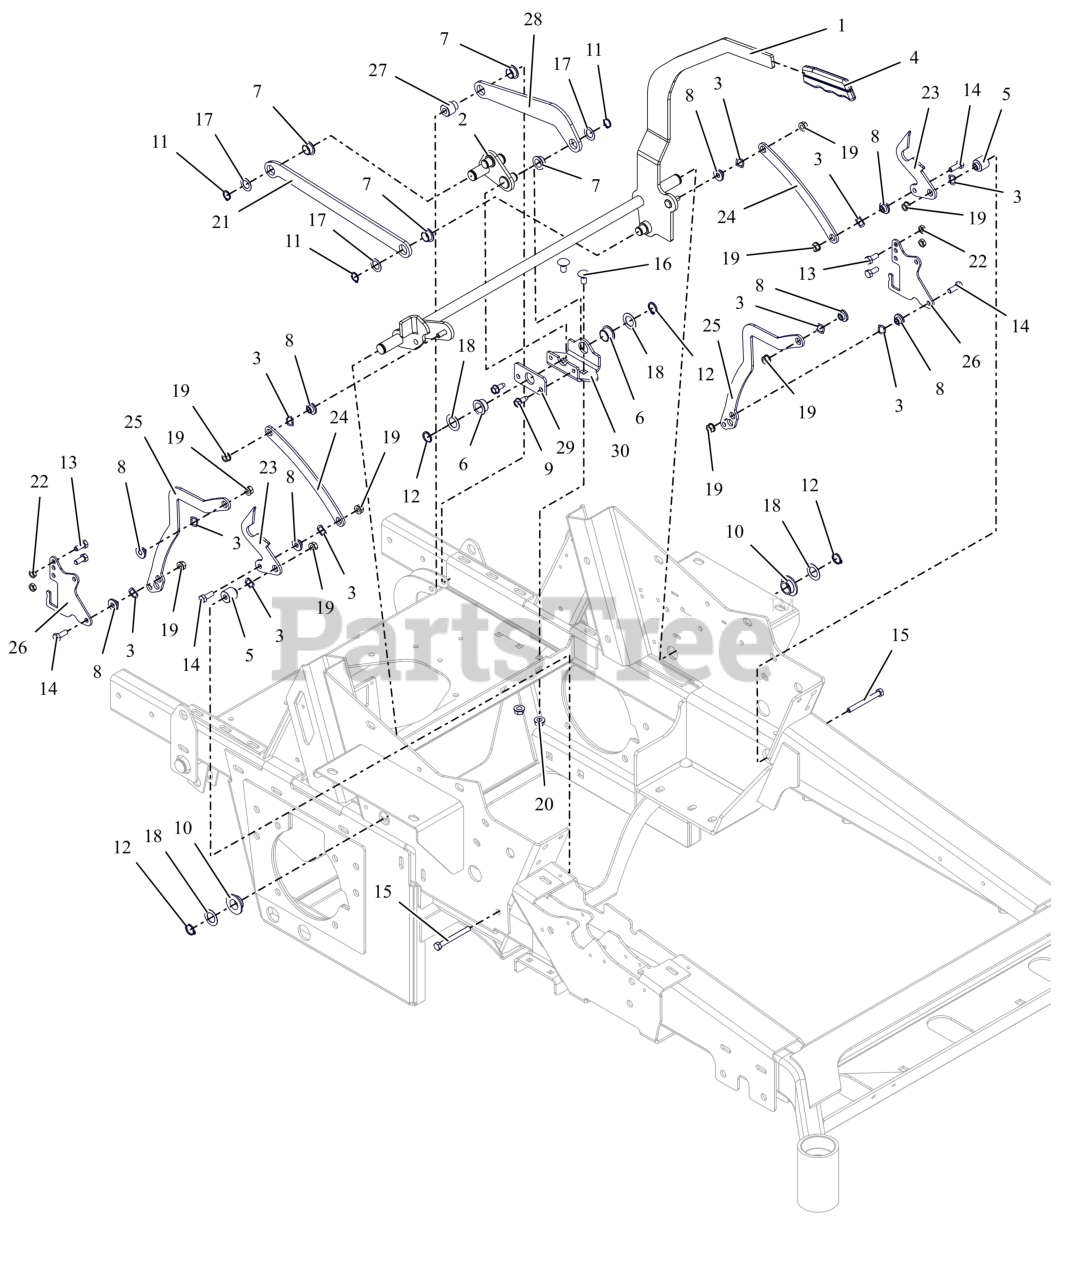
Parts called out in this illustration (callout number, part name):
1	WLDMT, PARKING BRAKE ARM
2	WLDMT, BRAKE ACTIVATION PIVOT
3	WAVE WASHER .531X.781X.125FH
4	GRIP, PARKING (GRAY)
5	BUSHING FLANGED - .318X.500X.972X.875
6	BSHG, FLANGE .750 X .875 X .5000 X 1.125
7	BSHG, FLANGE .625 X .750 X .375 X 1.000
8	BSHG-FLG .32X.500X.344X.880
9	SCR,TAP .312-18X.75 HWH TR ZCC
10	BSHG, FLANGED .762 X 1.48 X .44 IGLIDER
11	RG-RTNG-EXT .625X.050
12	RG-RTNG-EXT .689X.078
13	BLT,HEX .31-18X.75 G5 ZCC
14	BLT, HEX .31-18X.875 G5 ZCC
15	BLT, HEX .31-18X3.00 G5 ZCC
16	BLT, RHSN .38-16X.750 G5 ZCC
17	WSHR-THRST .625 X 1.0 X .03
18	WSHR-HDND-THRST .758X1.23X.031
19	NUT,LK-CTR-FLG .31-18 GF ZCC
20	NUT-LK-CTR-FLG .375-16 GF ZCC
21	LINK, BRAKE ACTIVATING FRONT
22	NUT-LK-CTR-JAM .312-18 GB ZCC
23	BRKT, BRAKE - RTN (BLACK)
24	BRKT, LINK - BREAK RTN (BLACK)
25	LINK- SPEED CONTROL -HTJ (BLK)
26	BRKT, SPEED - HTG (BLACK)
28	LINK, BRAKE ACTIVATION REAR
29	PLATE, BSHG MOUNTING
30	BRKT, BSHG MTG
